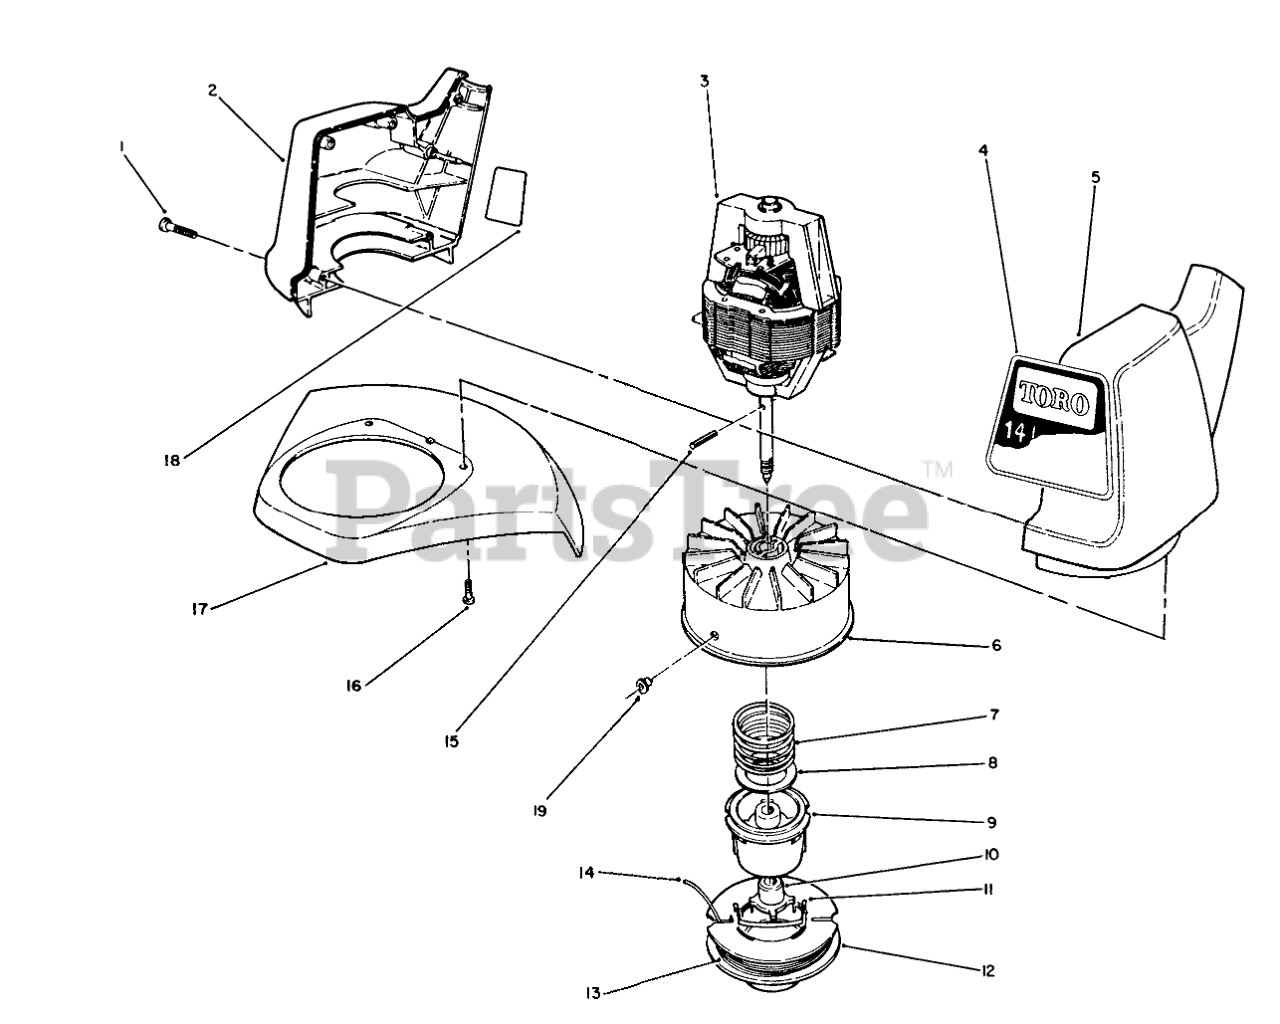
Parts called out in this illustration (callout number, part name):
1	SCREW-PPH
2	RH HOUSING, 1410
3	MOTOR, 1410 TRIMMER
4	1410 DECAL
5	LH HOUSING, 1410
6	Drum & Eyelet Assembly
7	SPRING COMPRESSION
8	WASHER-FLAT
9	SPOOL CORE
10	DRIVER
11	SADDLE-SPOOL CAP
12	Empty Spool
13	50-, .065" Dia. Cutting Line Prewound On Spool
14	50-, .065" Dia. Cutting Line In Coil
15	COIL PIN
16	SCREW-PPH
17	Shield Assembly
18	Decal
19	Eyelet
